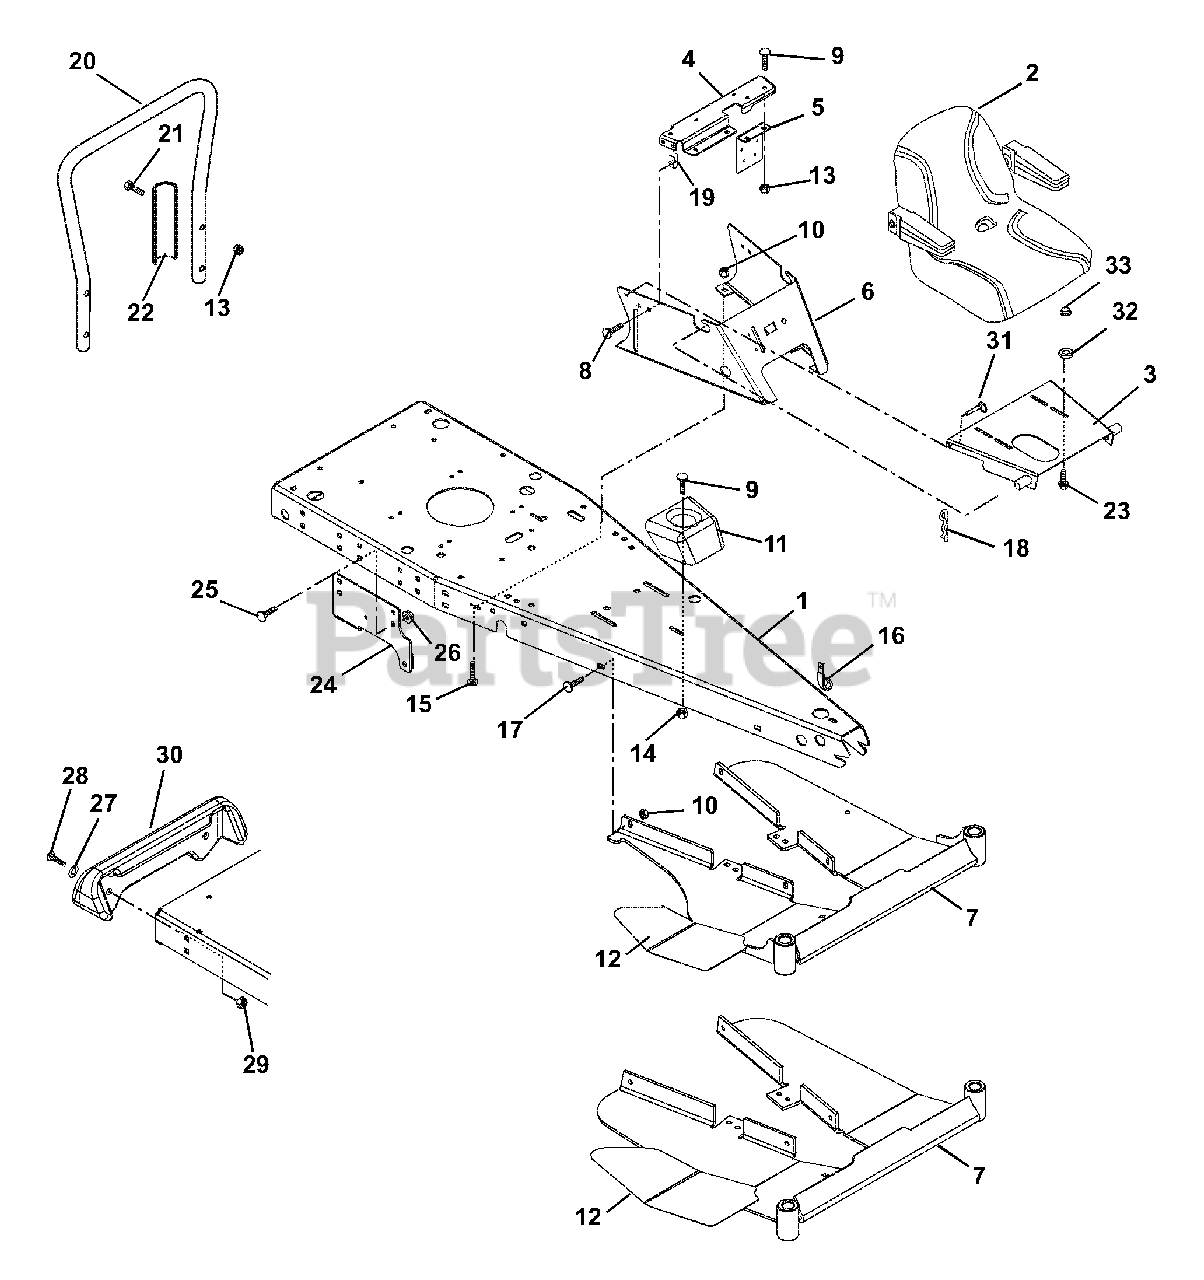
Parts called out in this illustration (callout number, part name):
1	FRAME,RER/SPORT-ZOOM
2	SEAT, TS2500 MICHIGAN W/ARM.
3	WLDM'T, SEAT PLATE
4	REINFORCEMENT, SEAT SUPPORT
5	PANEL-SOLENOID MOUNTING
6	SEAT SUPPORT
7	REST, RER/SZ FOOT
7	WLDMT-FOOTREST RER/MINI-Z-
8	BLT-SERHFWH .25-20X.75 YWZC
9	BLT-RDHDSQNK .31-18X.75 G5BZ
10	NUT-LK-TOP-FLG .38-16 BLKZC
11	CUP HOLDER RER
12	GRIP, LEFT FOOT REST
12	GRIP, RER FOOTREST (LH)
12	GRIP, RH FOOT REST
13	GRIP, RER FOOTREST (RH)
13	NUT-LK-TOP-FLG .31-18 BLKZC
14	@NUT-SPNLK-FLG .312-18 YWZC
15	BLT-RDHDSQNK .38-16X.75 G5BZ
16	J-CLAMP
17	BLT-RDHDSQNK .38-16X1.00 G5BZ
18	PIN-HAIR-EXT .12X.31X2.37 YWZC
19	NUT-RTNR .25-20X.56
20	TUBE
21	@BLT-HEX .31-18X1.50 GR5 YWZC
22	BRACE
23	BLT-SERHFWH .31-18 X 1 YWZC
24	BRKT, TRANS (RH-WLDMNT)
24	BRKT, TRANS (LH-WLDMNT)
25	BLT-RDHDSQNK .38-16X.75 G5BZ
26	NUT-LK-TOP-FLG .38-16 BLKZC
27	@WSHR-FL-STL.438X1.00X.083 YWZ
28	@BLT-HEX .38-16X1.75 GR5 YWZC
29	NUT-LK-TOP-FLG .38-16 BLKZC
30	WEIGHT, SPORT-Z
31	PIN-DET W/RING .25X1.00
32	SPACER, .344X1.00X.410
33	NUT-PUSH .312
